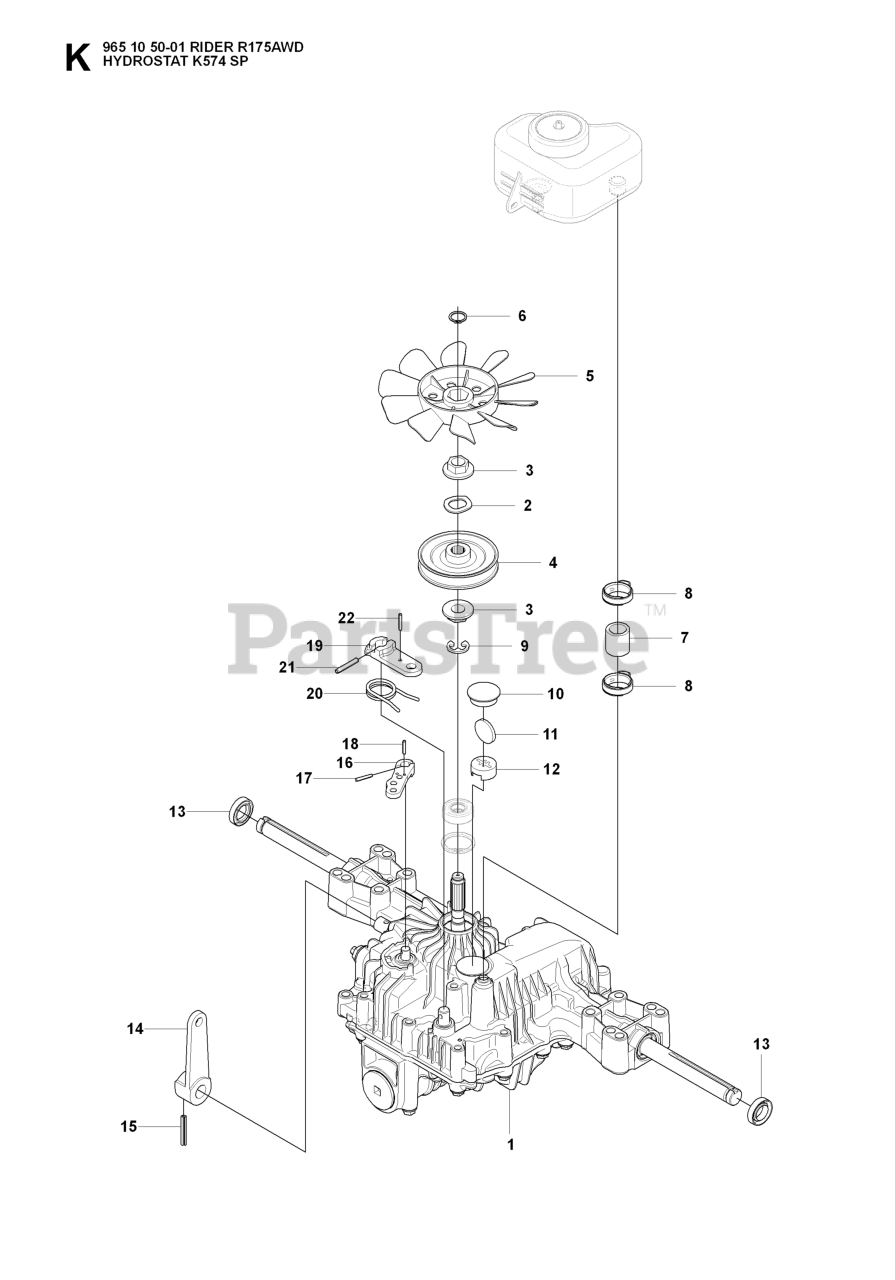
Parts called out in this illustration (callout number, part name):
1	HYDRAULMOTOR
4	PULLEY - 3 1/2"
5	FAN.BLACK.1A646083070
6	RETAINING RING **
7	PIPE
8	CLAMP
9	Retaining Ring
13	RP SEAL.19, 19216334280
20	RETURN SPRING
